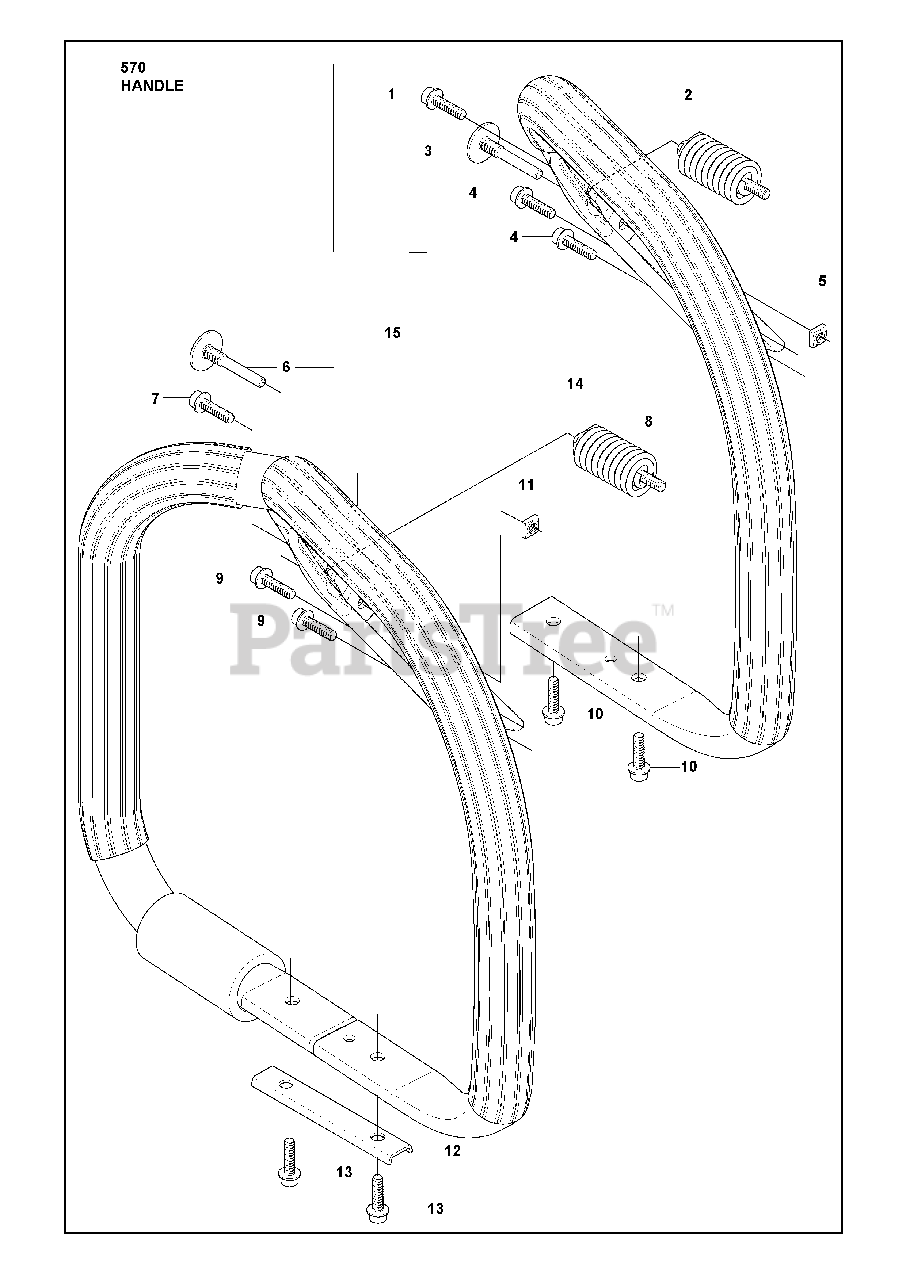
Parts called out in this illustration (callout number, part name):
2	ANTIVIBE MOUNT
8	ANTIVIBE MOUNT
14	FRONT HANDLE ASSY
15	HANDLE
